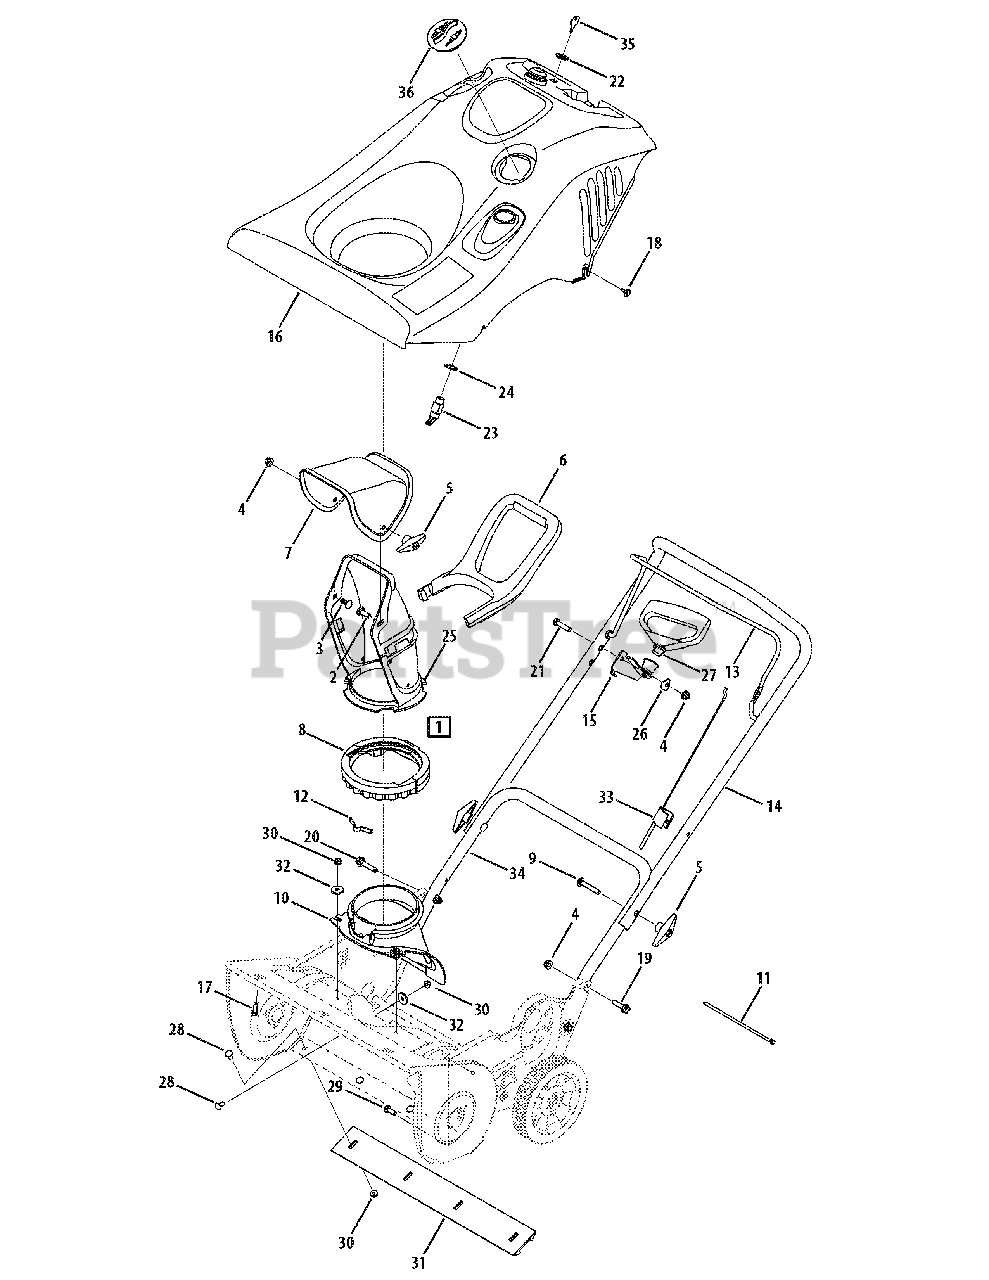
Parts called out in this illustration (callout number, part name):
1	Chute Assembly (Incl. Ref. 37-41)
2	Carriage Bolt 5/16-18 x 1.0"
3	Carriage Bolt 5/16-18 x 0.750"
4	Flange Lock Nut, 5/16-18
7	Upper Chute
8	Ring-Lower Chute
9	Carriage Bolt 5/16-18 x 2.0 Gr. 5
10	Chute, Adapter 5" Dia
12	Chute Adjustment Spring
15	Mitten Grip Bracket
16	Shroud Assembly, Gray (Incl.Spark Plug Cover)
17	Screw, 1/4-15 x .75
18	Screw, #10-16 x .625"
19	Hex Flange Screw, 5/16-18 x 1.25
20	Hex Flange Screw 5/16-18 x 1.50
21	Hex Screw, 5/16-18 x 1.5
22	Hex Nut 5/8-32 x .12 Special
23	Key Switch-Electric Start
24	Lock Washer Internal .625 x 1.058
25	Lower Chute 5" Dia.
26	Saddle Washer .320 x .93
27	Recoil Handle, Mitten
28	Screw, 1/4-20 x .62
29	Truss Machine Screw, 5/16-18 x .75
30	Hex Flange Lock Nut, 1/4-20
31	Shave Plate, 19.88
32	Flat Washer .265 x .938 x .120
33	Control Cable
35	Ignition Key
36	Spark Plug Cover, Gray
36	Spark Plug Cover, Black
